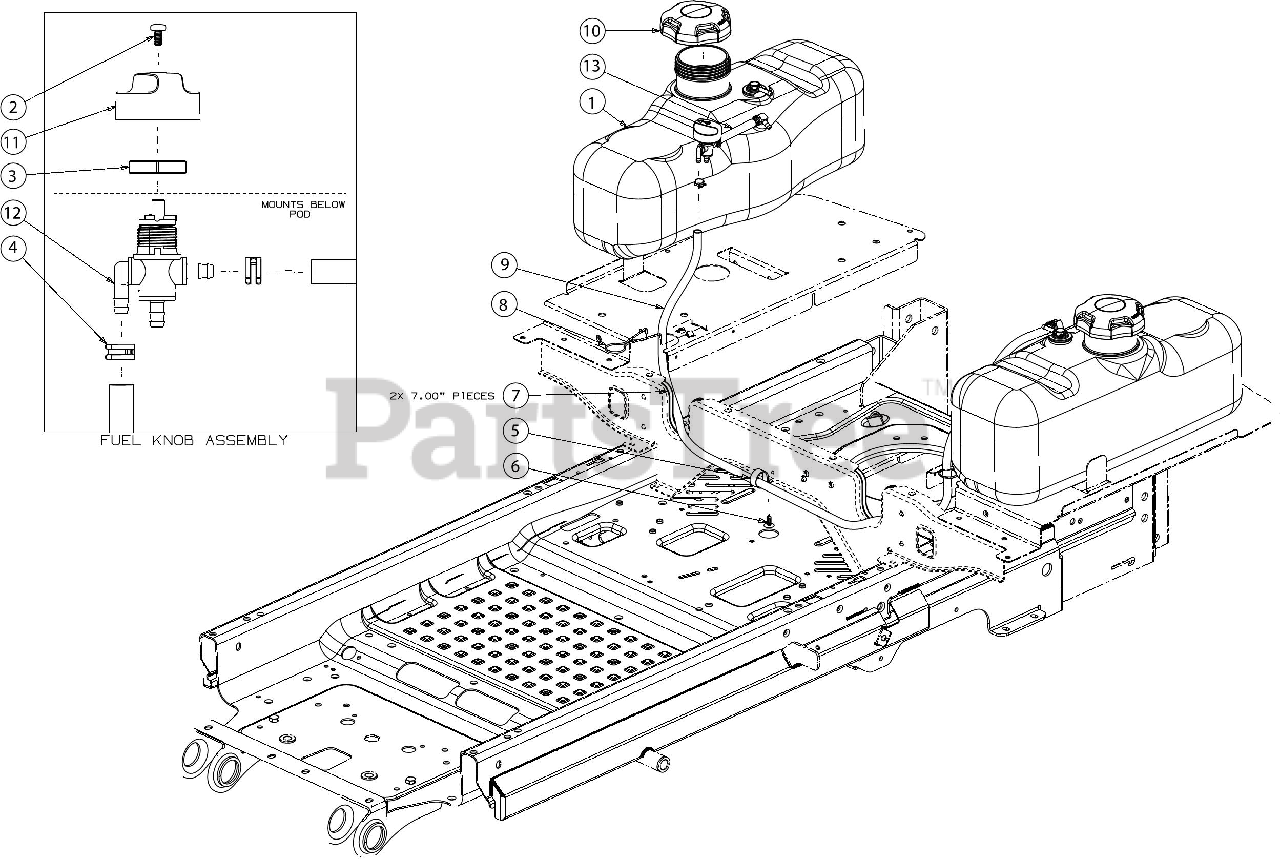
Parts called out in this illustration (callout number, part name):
1	FUEL TANK 3.50 GAL
1	RUBBER GROMMET 23.0 ID X 35.5 OD
1	FUEL PICKUP FITTING
1	ROLLOVER FUEL VALVE
2	SCREW-M4-0.7 X 8MM
3	3 WAY SELECT NUT
4	HOSE CLAMP 1/20
5	DRAIN HOSE CLAMP
6	RATCHET CLIP .250
7	TRIM STRIP
8	TANK SUPPORT ROD
9	FUEL HOSE LOW PERMEATION
10	FUEL CAP 3.5 W/TETHER"
11	FUEL CAP 3 WAY
12	3-WAY FUEL SELECT SWITCH
13	FUEL HOSE LOW PERMEATION
